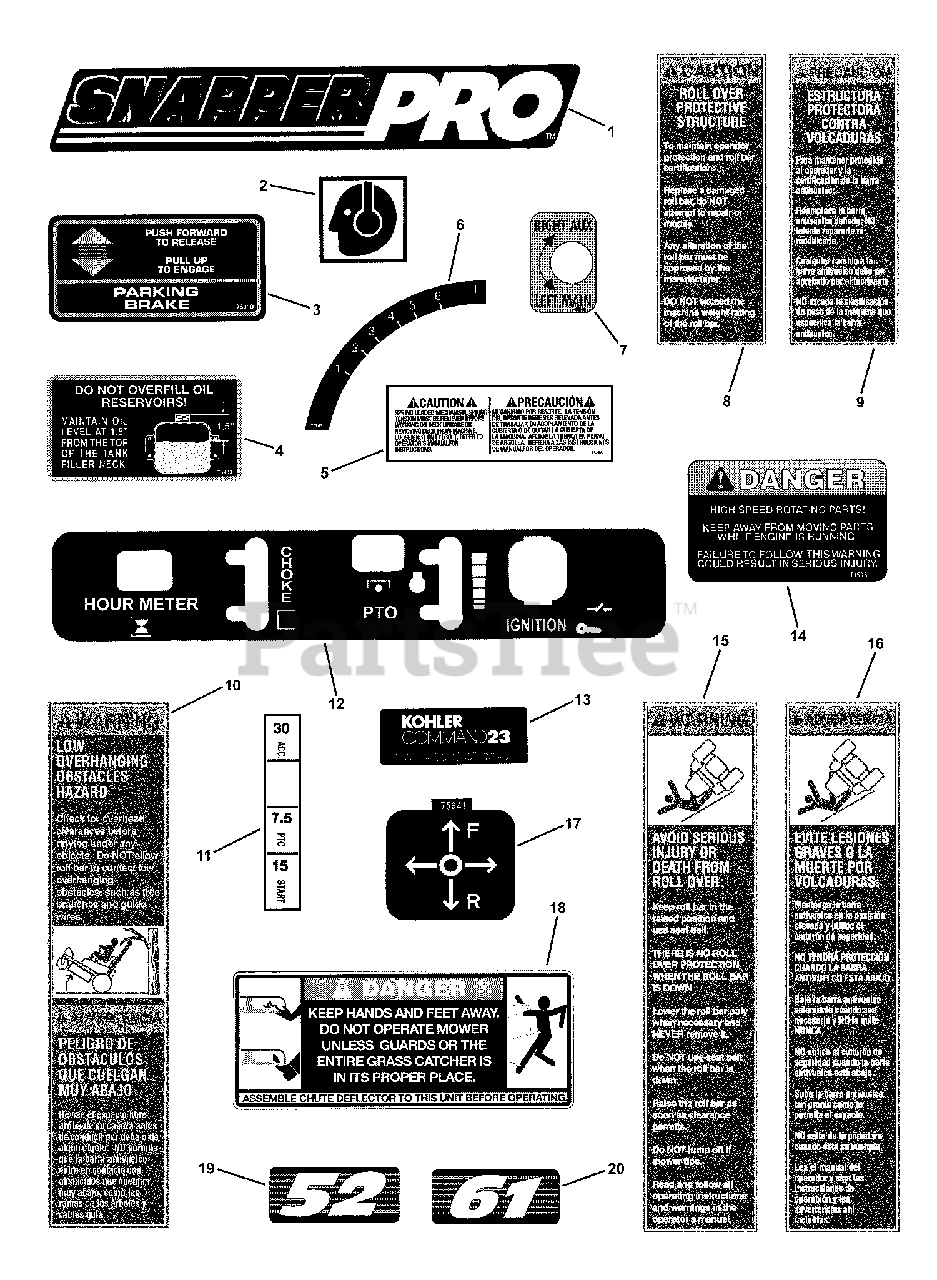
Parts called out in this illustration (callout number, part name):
1	DECAL, Snapper Pro
2	DECAL, Ear Protection
3	DECAL, Park Brake
4	DECAL, Oil Reservoir Overfill Warning
5	DECAL, Caution (Spring Mechanism)
6	DECAL, Detent
7	DECAL, Tank Selector
8	DECAL, Caution ROPS
9	DECAL, Caution ROPS (Spanish)
10	DECAL, ROPS Overhang
11	DECAL, Fuse
12	DECAL, Control Panel
13	DECAL, 23HP Kohler Engine
14	DECAL, Danger (High Speed Rotating Parts)
15	DECAL, Warning ROPS
16	DECAL, Warning ROPS (Spanish)
17	DECAL, Lever Control
18	DECAL, Danger, Guard/Catcher
19	DECAL, 52" Deck (silver)
20	DECAL, 61" Deck (silver)
